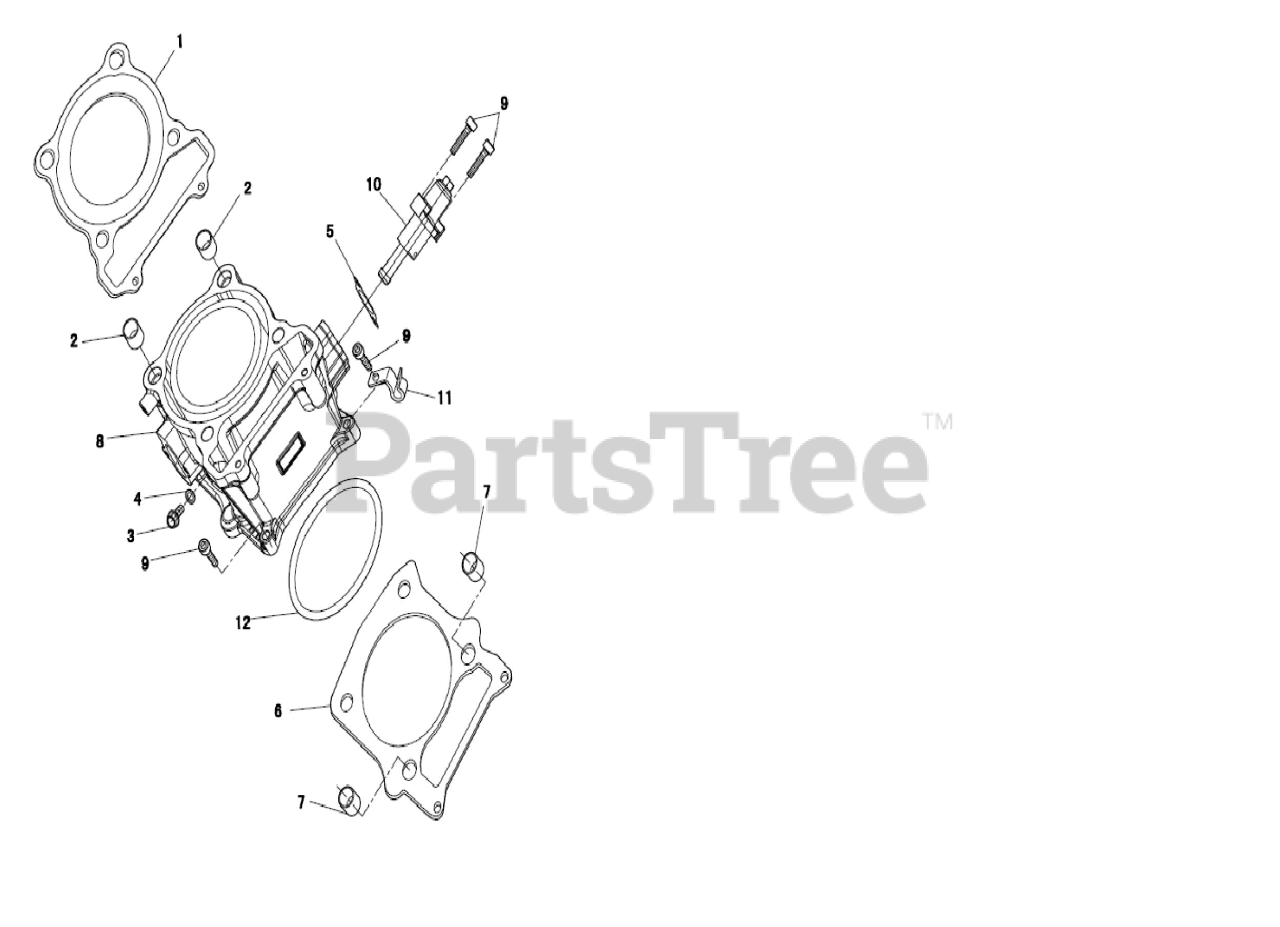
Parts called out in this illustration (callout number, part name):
1	HEAD GASKET
2	Pin,Dowel 12X16
3	Hex flange bolts M6X12
4	Aluminum Washer 6X12X1.5
5	TENSIONER GASKET
6	CYLINDER GASKET
7	Pin,Dowel 14X16
8	CYLINDER ASSEMBLY
9	Hex head cap screw M6X25
10	TENSIONER ASSEMBLY
11	Pipe Clamp ?
12	O-RING 90 X 3
